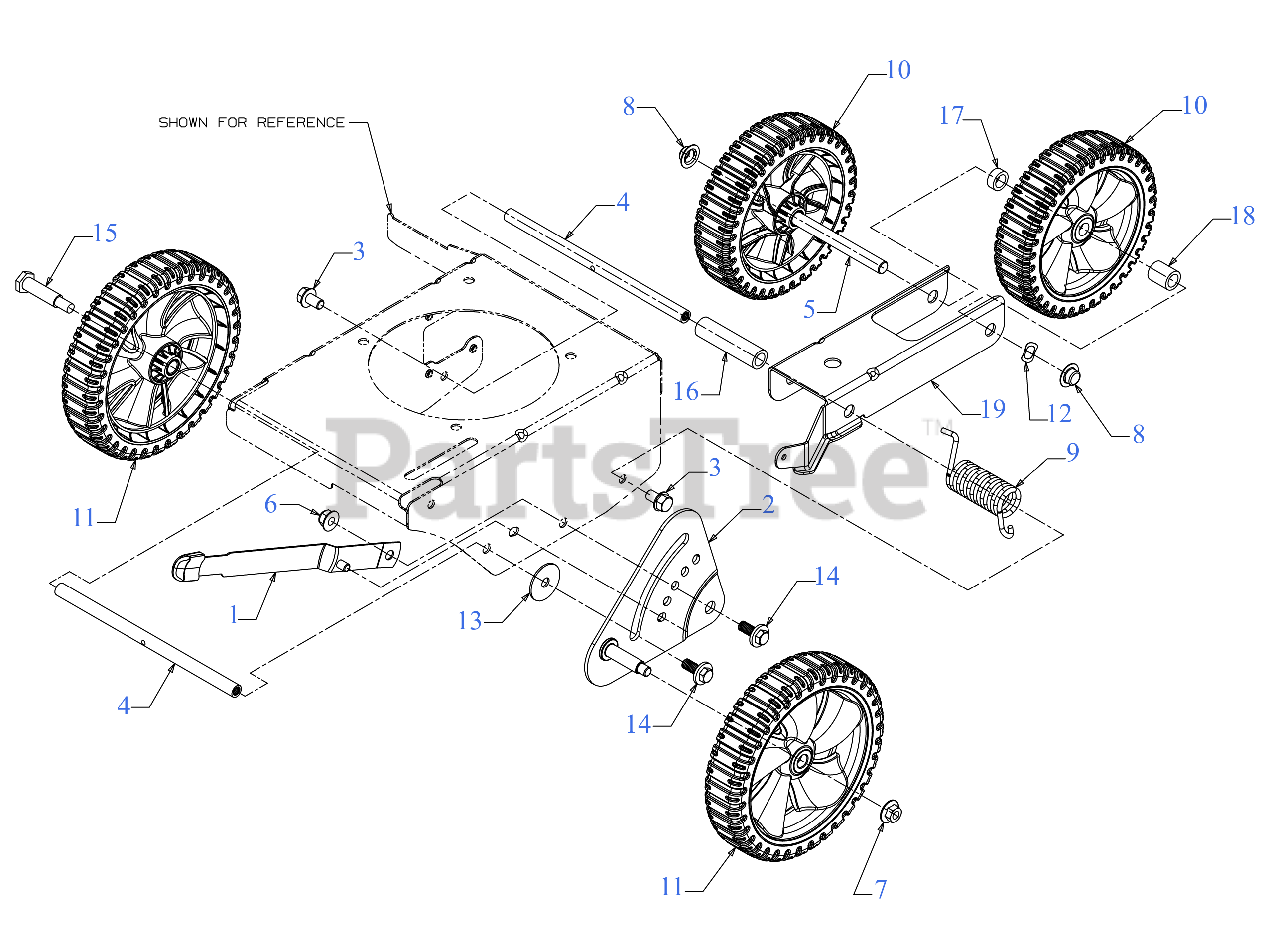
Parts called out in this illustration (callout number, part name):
1	WHEEL ADJUSTMENT LEVER ASSEMBLY
2	HEIGHT ADJUMENT ASSEMBLY
3	SCREW 3/8-16X.625 GR 5
4	SPACER .50 x 9.25
7	FLANGE LOCK NUT
8	PUSH CAP
9	TORSION SPRING
10	WHEEL (8 X 1.8) (SBD GRAY)
11	WHEEL (7 X 1.8) (SBD GRAY)
12	WAVE WASHER
13	FLAT WASHER .390 ID x 1.50 OD x .075
15	SHOULDER BOLT .498 DIA. x 1.64
16	SPACER
17	SPACER
18	SPACER
